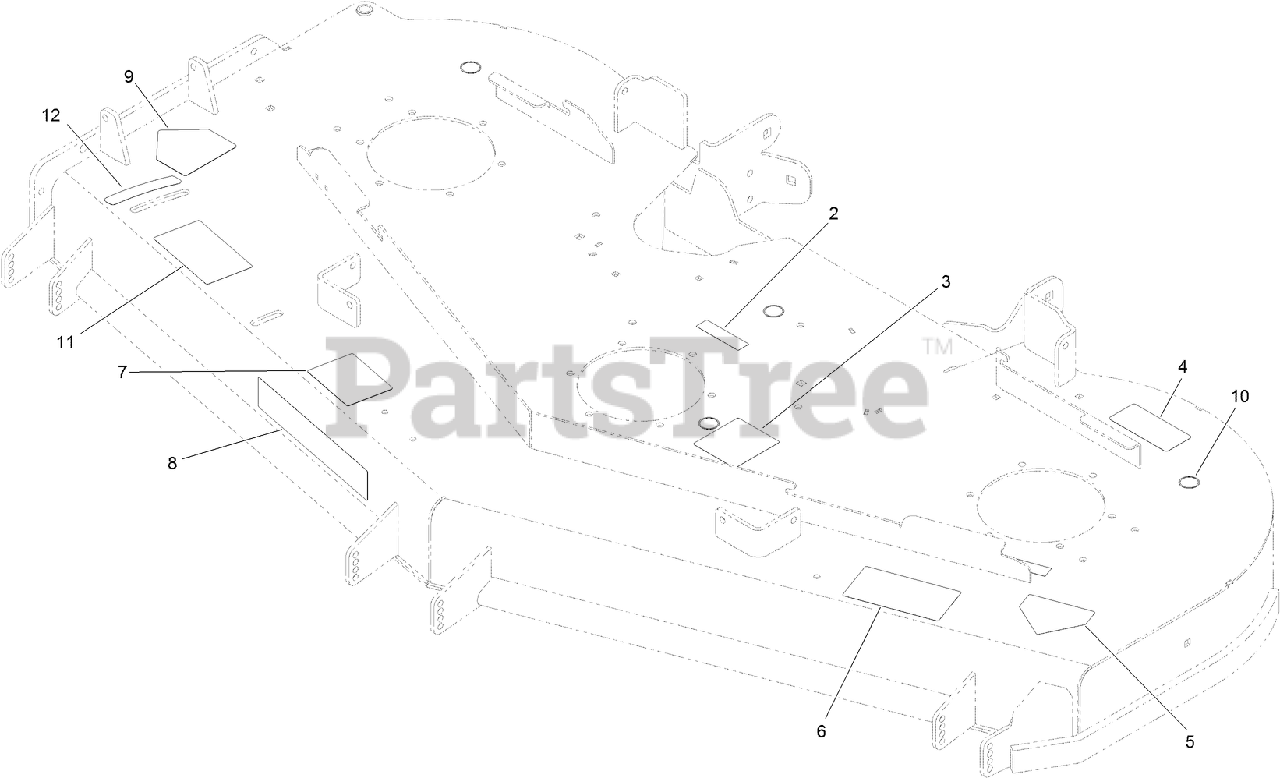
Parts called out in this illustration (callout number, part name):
2	DECAL-COVER, MISSING
3	DECAL-ROUTING, DECK BELT
4	DECAL-TORQUE
5	DECAL-DANGER
6	DECAL-DANGER, THROWN OBJECT
7	DECAL-SCALP, ANTI
9	DECAL-DANGER
10	DECAL-GREASE
11	DECAL-ADJUSTMENT, BAFFLE
12	DECAL-SETTING, BAFFLE
